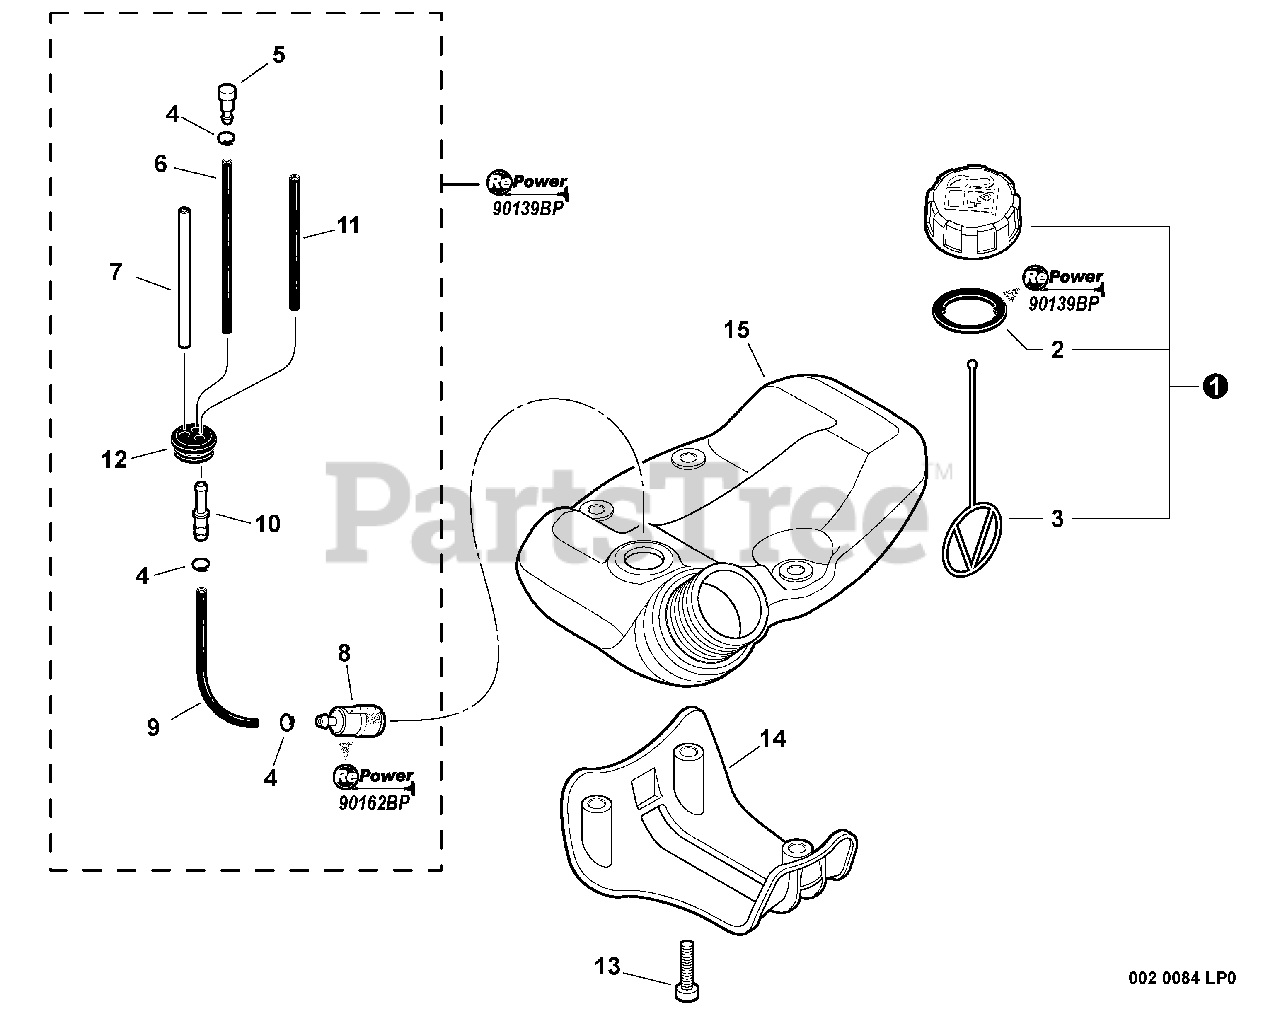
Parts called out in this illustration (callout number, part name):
1	CAP ASSY, FUEL
2	GASKET, FUEL CAP
3	CONNECTOR, CAP L= 123
4	CLIP Ø6
5	VENT ASSY
6	PIPE, FUEL 3×5×90 BLACK
7	PIPE, FUEL 3×6×80 CLEAR
8	FILTER, FUEL
10	CONNECTOR, PIPE Ø5ר3.5
11	PIPE, FUEL 3×5×74 BLACK
12	GROMMET, FUEL Ø5
13	BOLT, TORX 5×25
14	GUARD, FUEL TANK
15	TANK, FUEL
16	TUNE-UP KIT - REPOWER
17	FUEL SYSTEM KIT
